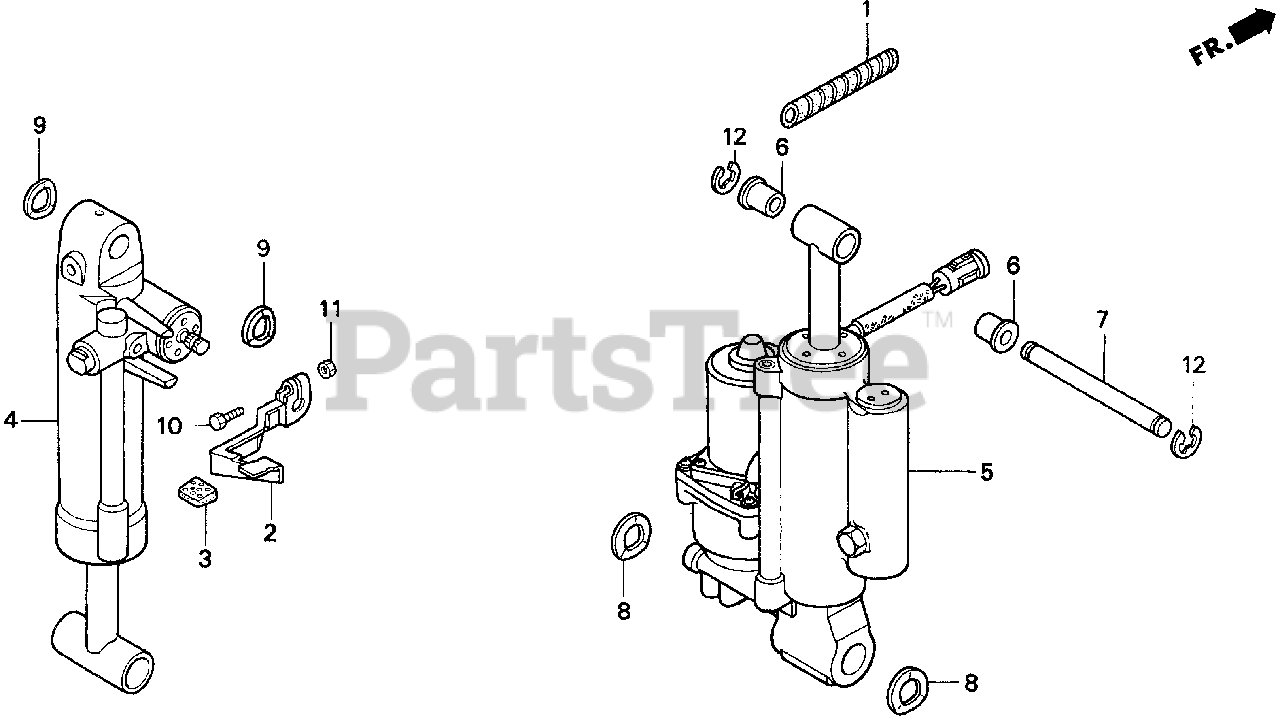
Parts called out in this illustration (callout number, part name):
2	LEVER, TILT
3	GRIP, LEVER
4	SHOCK ABSORBER ASSY. *NH283* (STIN GRAY)
6	BUSH, CYLINDER (UPPER)
7	PIN, CYLINDER (UPPER)
9	WASHER, WAVE (24MM)
10	BOLT, HEX. (6X25)
11	NUT, HEX. (6MM)
12	E-RING (10MM)
